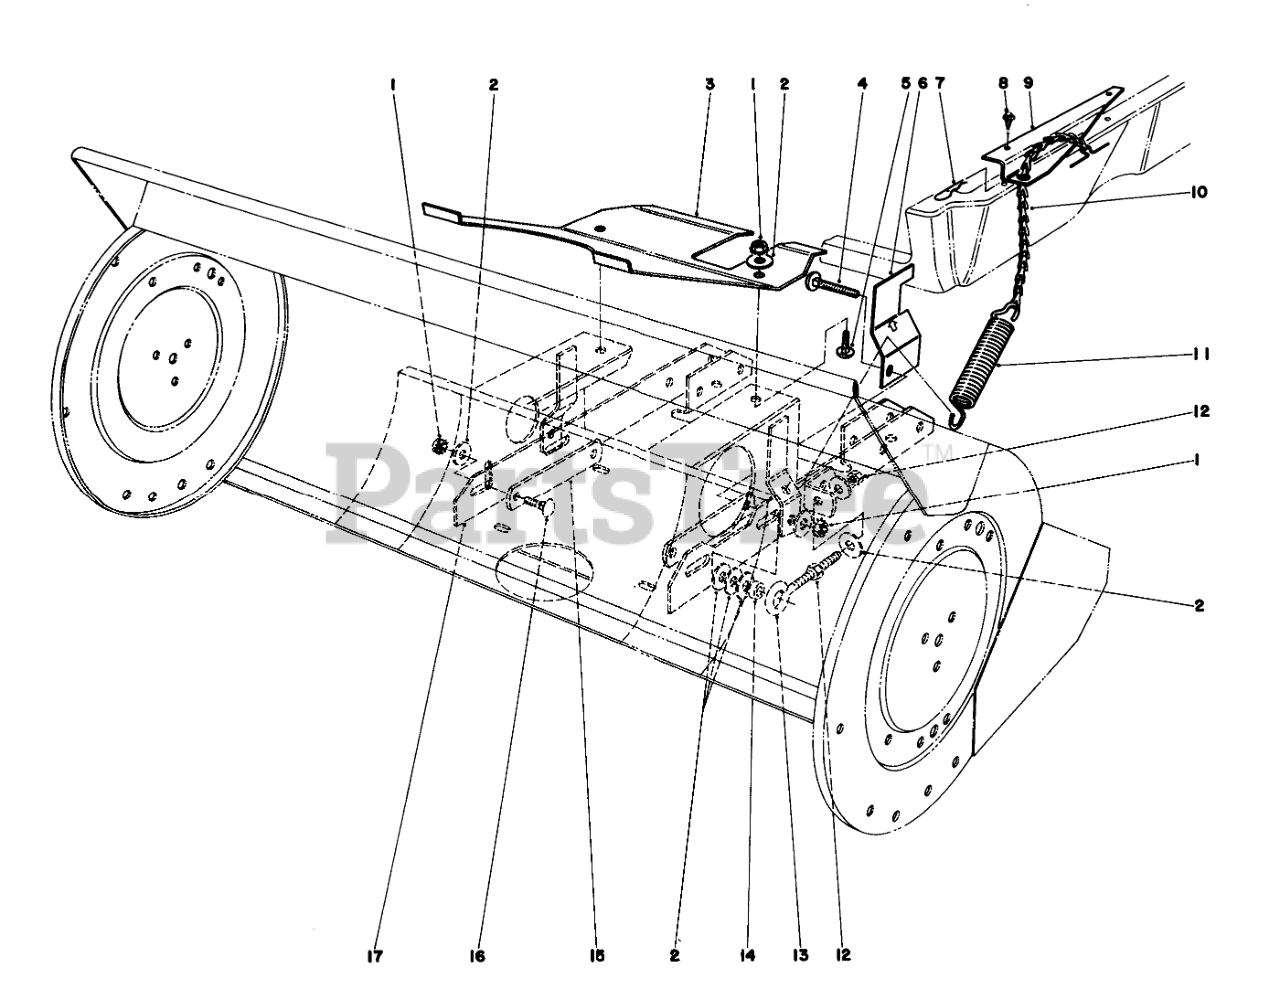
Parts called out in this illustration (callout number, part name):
1	NUT-KEPS
2	WASHER-FLAT
3	Guard-Drive Pulley
4	SCREW-CARR
5	SCREW-CARR
6	Bracket-Belt Adjust Guide
7	PIN-HAIR
8	SCREW-HWHTF
9	Plate-Lift Spring Anchor
10	CHAIN & TOGGLE ASM
11	IDLER ARM SPRING
12	NUT-HEX
13	Eye Bolt
14	Spacer
15	Strap-Header Channel
16	BOLT-CARR
17	Pivot Bracket
